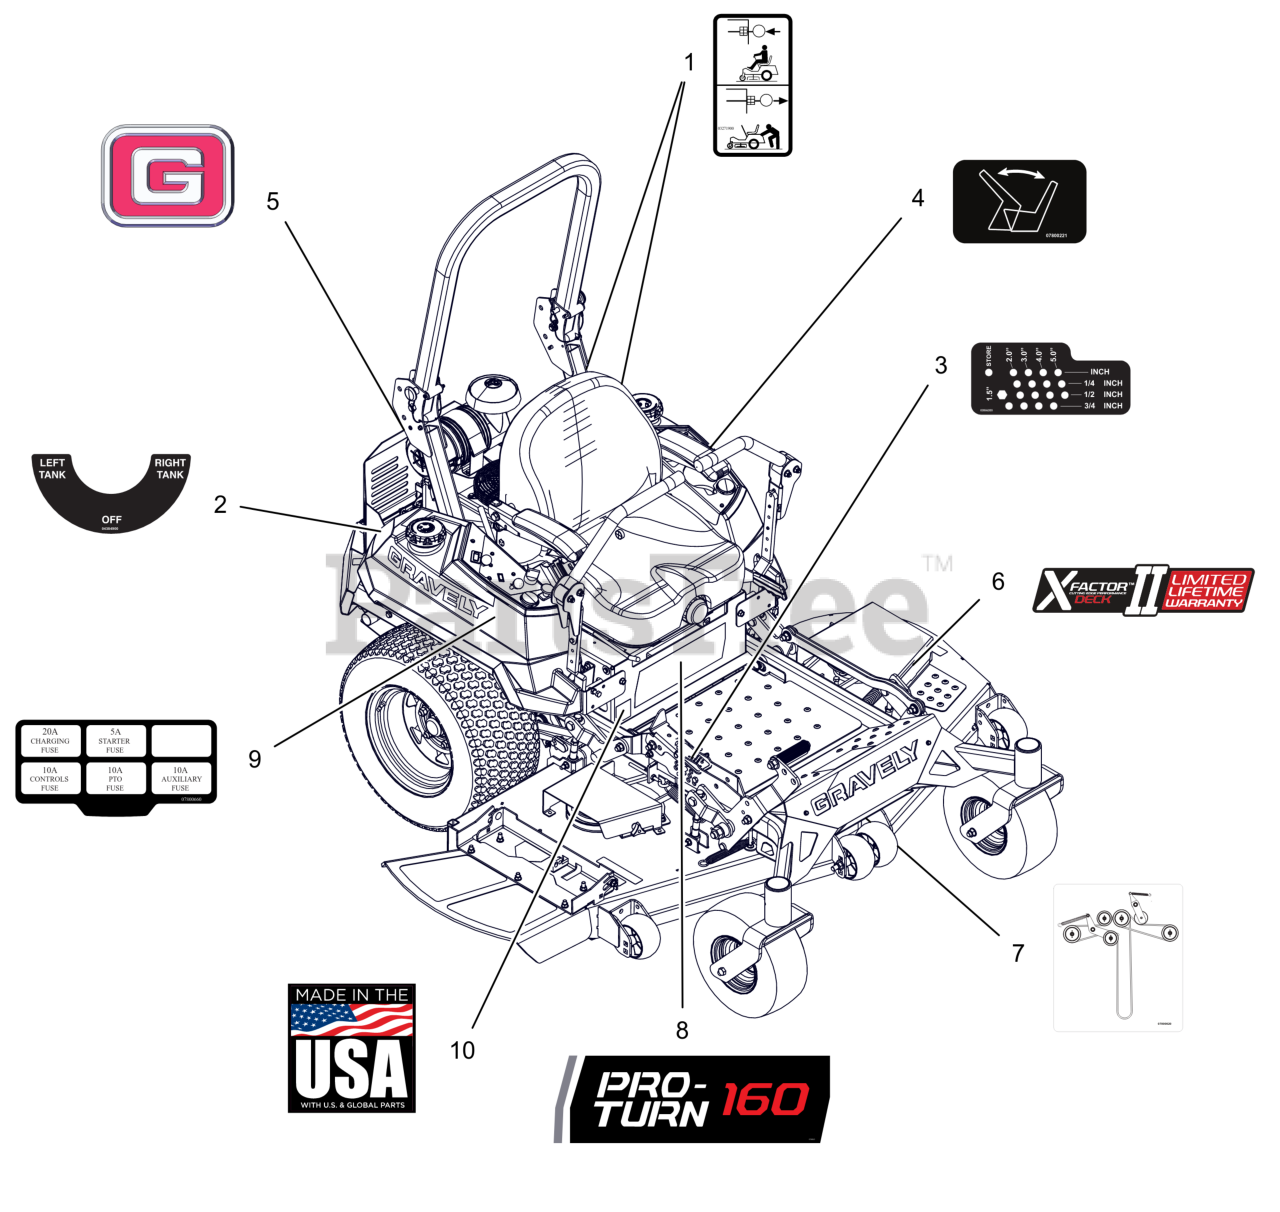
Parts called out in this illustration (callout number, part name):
1	DECAL, TRANSMISSION DISCONNECT
2	DECAL, FUEL VALVE
3	DECAL, HEIGHT OF CUT
4	DECAL - SEAT RELEASE
5	DECAL, GRAVELY BRAND
6	DECAL, X-FACTOR DECK
7	DCL,BELT ROUTE-RH BK-SIDE IDLR
8	DECAL, PRO-TURN 160
9	DECAL, FUSE BLOCK
10	DECAL, MADE IN USA
